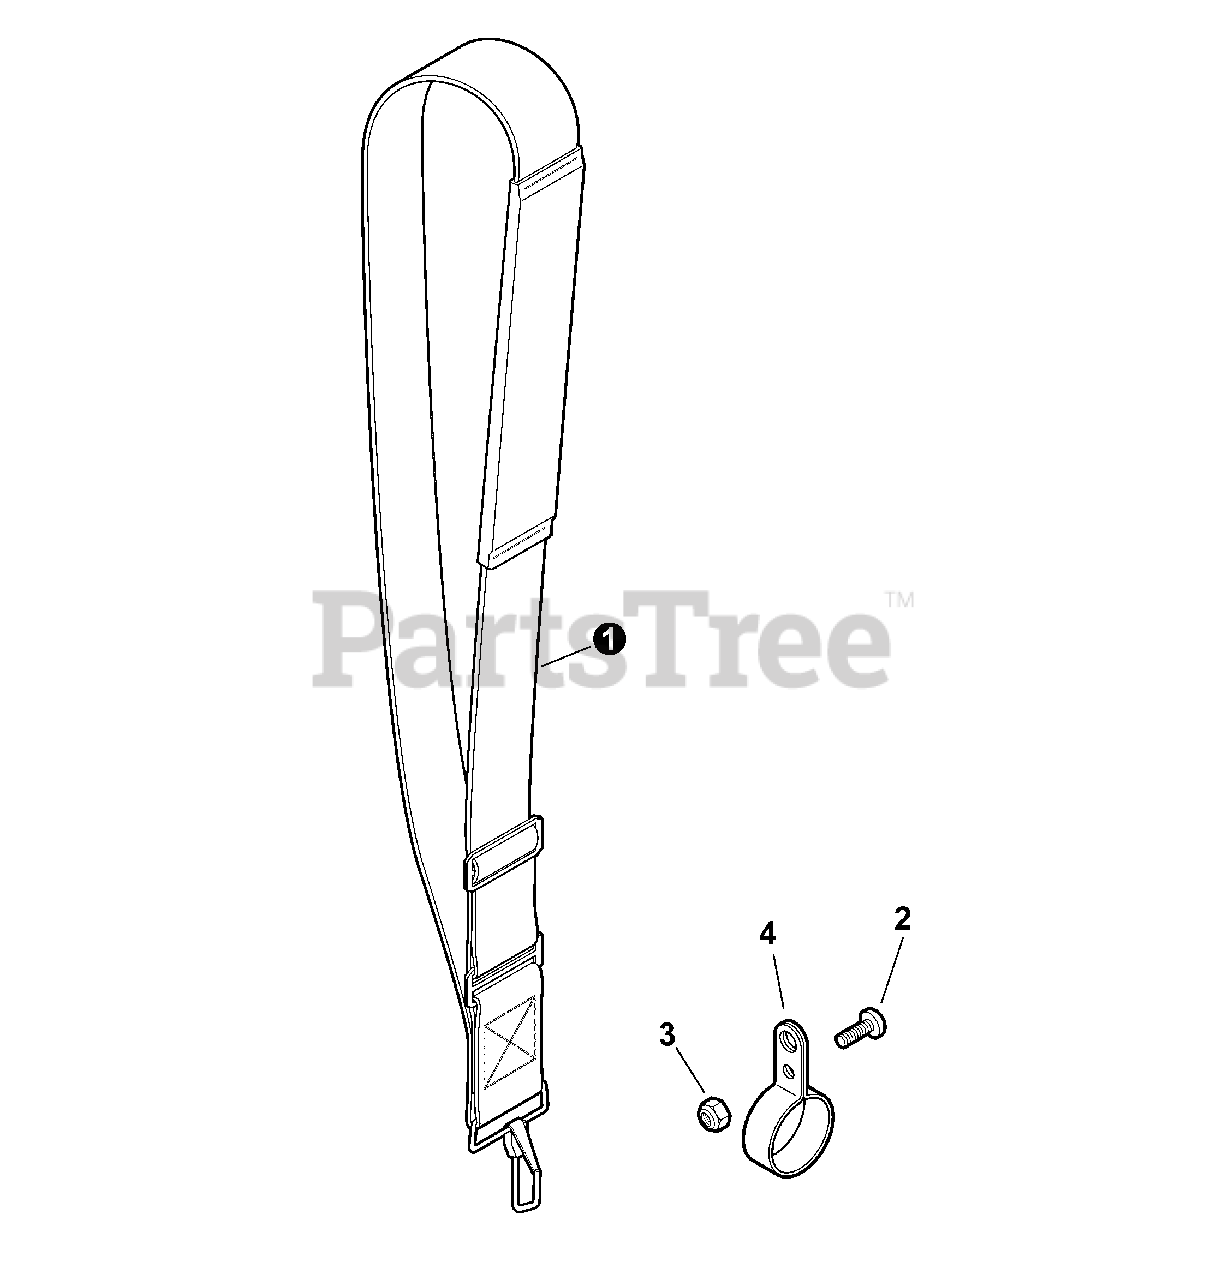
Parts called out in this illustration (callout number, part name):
1	STRAP ASSY, SHOULDER
2	BOLT, TORX 5×10
3	NUT, LOCK M5
